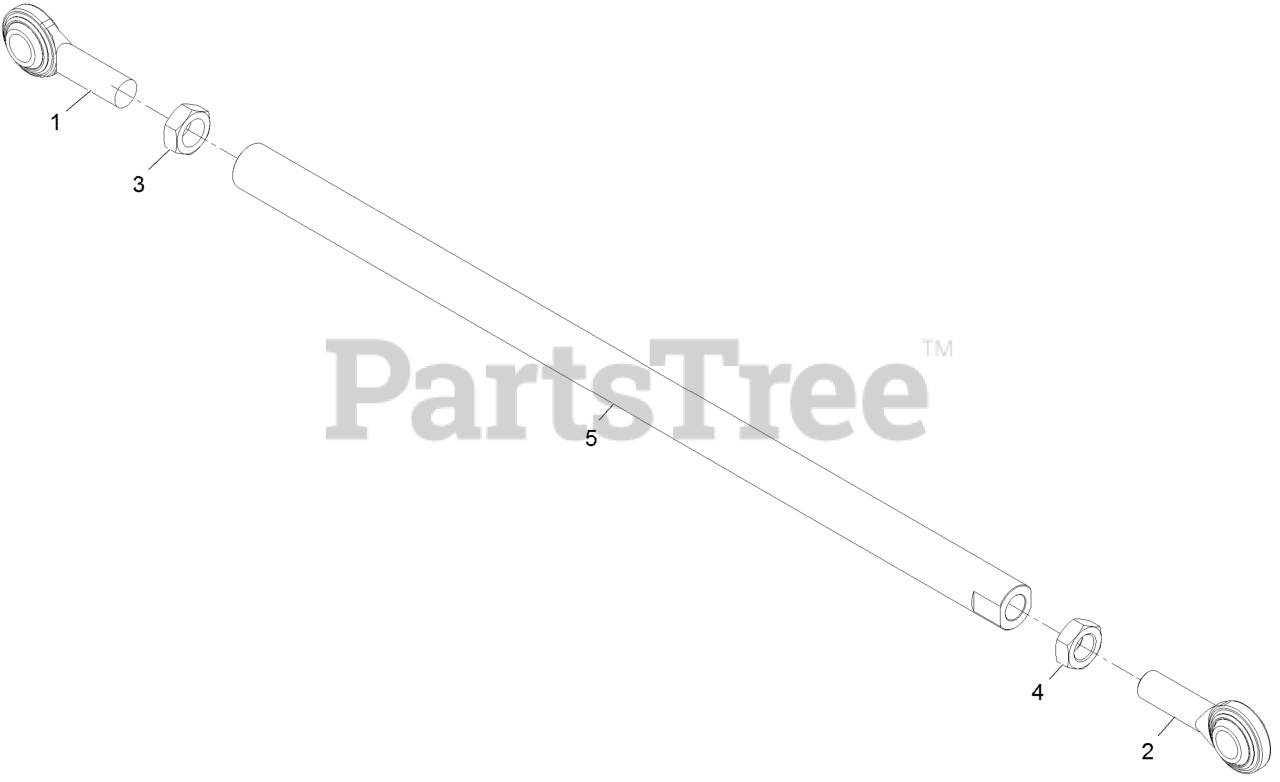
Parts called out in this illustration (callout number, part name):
1	BALLJOINT-SPHERICAL
2	BALLJOINT-SPHERICAL
3	NUT-JAM
4	NUT-JAM
5	LINK-HEIGHT OF CUT
